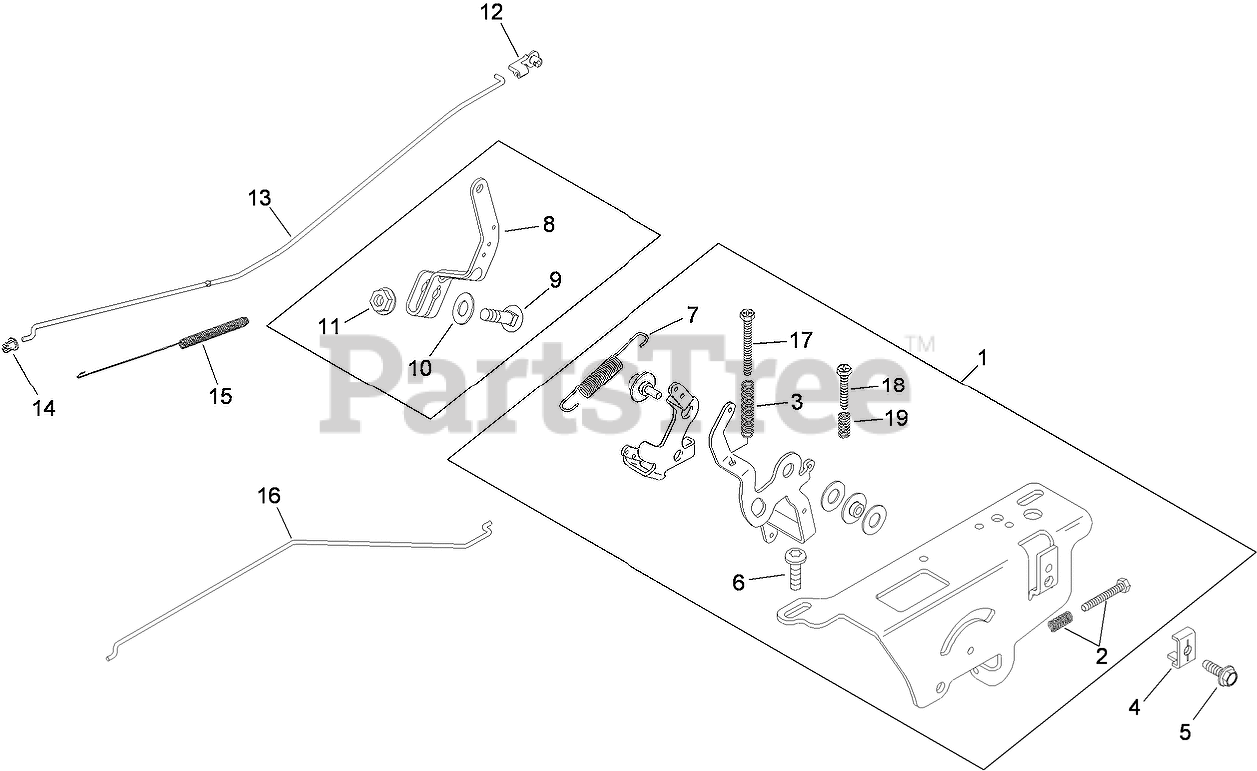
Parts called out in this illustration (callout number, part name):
1	SPEED CONTROL ASM (INCLUDES REF 2, 3, 6 QTY 1], 7, 17, 18, 19)
2	IDLE ADJUSTING SCREW AND SPRING KIT
3	SPRING-CONTROL, SPEED (LONG)
4	CLAMP-CABLE
5	SCREW-FLANGE, THREAD FORMING (M5X0.8X16)
6	Screw-Socket, 6 Lobed (Thread Forming, M6x1.0x20)
7	Spring-Governor
8	GOVERNOR LEVER ASM (INCLUDES REF 9-11)
9	Bolt-Square Neck, Round Head (1/4-20x1)
10	Washer-Lock, Internal Tooth (1/4)
11	Nut-Flange, Hex (1/4-20)
12	BUSHING-RETAINING, LINKAGE
13	LINKAGE-THROTTLE
14	BUSHING-LINKAGE, THROTTLE
15	Spring-Linkage
16	Linkage-Choke (Single Wire)
17	SCREW-PHL THD FRM (M4X0.7X38)
18	Screw-Thread Forming (M4x0.7x25)
19	Spring-Control, Speed
